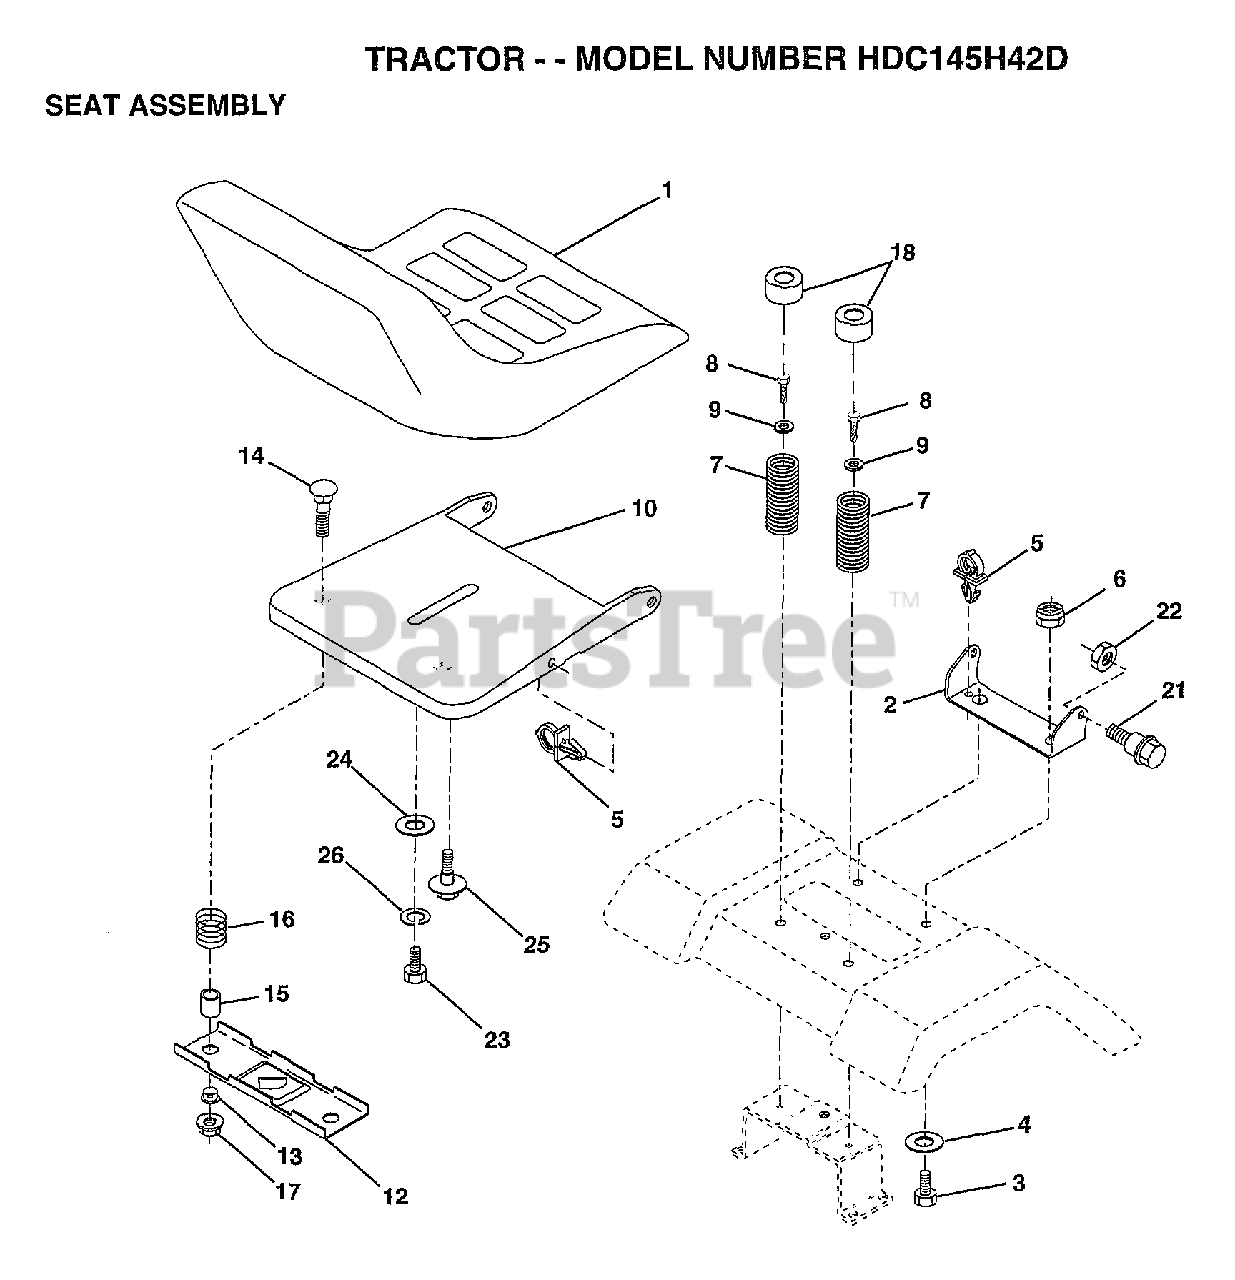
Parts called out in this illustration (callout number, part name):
1	SEAT
2	BRACKET PVT SEAT
3	BOLT
4	WASHER PM
5	CLIP.PUSH-IN.HING
6	NUT
7	SPRING COMPRESSIO
8	SCREW GTV
9	WASHER
10	PAN-SEAT
12	BRKT SWITCH
13	BUSHING
14	BOLT-RD HD SQ NK
15	SPLIT SPACER
16	SPRING
18	CAP SPRING
21	"BOLT,SHOULDER"
23	BOLT
24	WASHER
25	"BOLT,SHOULDER"
26	LOCKWASHER
